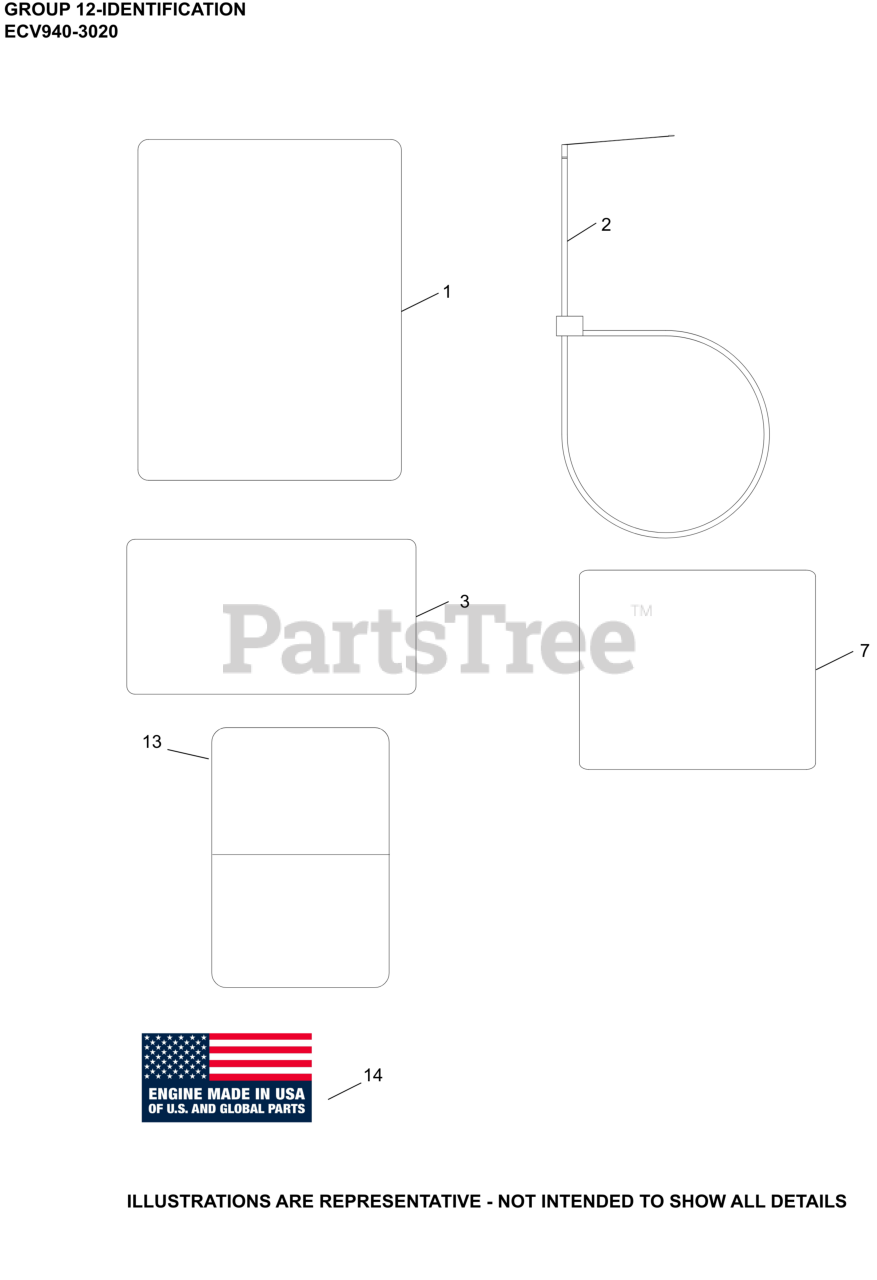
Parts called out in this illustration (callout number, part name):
1	LABEL, CLEAR LAMINATION
3	LABEL, EFI FUEL FILTER
7	DECAL, HDAC
13	HOT SURFACE DECAL
14	DECAL, USA
